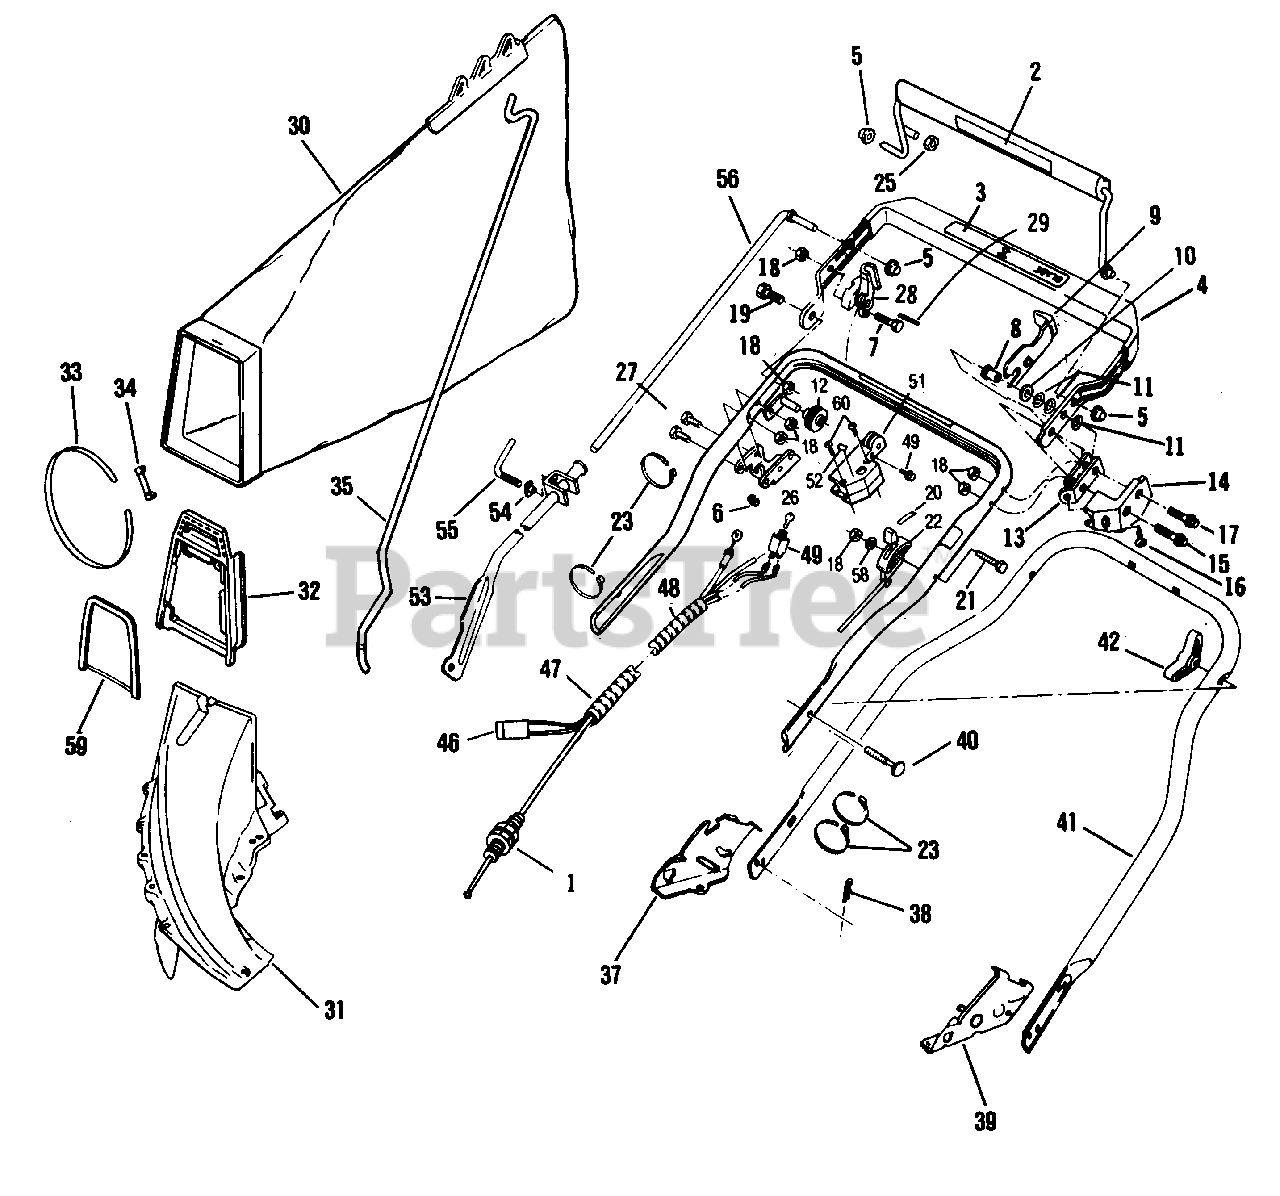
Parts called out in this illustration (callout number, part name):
1	Control Cable Assembly
2	Decal-Blade Control
3	Decal-Drive Control
4	Top Handle and Grip Assembly
5	Pushnut
6	Ring-Retainer
7	Bolt-Hex
8	Spacer-Flanged
9	Lever-Lockout
10	Washer-Plain
11	Washer-Spring
12	Pulley
13	Down-Stop
14	Guard-Lockout
15	Bolt-Shoulder
16	Screw
17	Bolt-Shoulder-L.H.
18	Locknut
19	Bolt-Shoulder-R.H.
20	Decal-Throttle
21	Screw-Throttle Mtg.
22	Control Assembly-Throttle
23	Tie Strap
24	Control Lever and Nut Assembly
25	Nut-Acorn
26	Bracket-Clutch Cable
27	Screw-Clutch Cable Brkt.
28	Cam
29	Roll Pin
30	Bag Assembly
31	Chute Assembly
32	Adapter-Chute
33	Strap
34	Lock-Strap
35	Rod-Grass Bag
36	Pivot-Bracket Pulley
37	Bracket-Handle-R.H.
38	Hair Pin
39	Bracket-Handle-L.H.
40	Screw
41	Handle Section-Bottom
42	Knob
43	Handle Section-Center
44	Decal-Drive Lockout
45	Decal-Starting Inst.
46	Wire Harness Assembly
47	Spiral Tubing
48	Spiral Tubing
49	Switch Assembly
50	Screw
51	Cover
52	Decal
53	Control Lever Assembly
54	Nut-Control Lever Clamp
55	Lever-Rod Clamp
56	Rod-Control
57	Key Switch (2)
58	Washer
59	Brace, Chute
60	Screw
